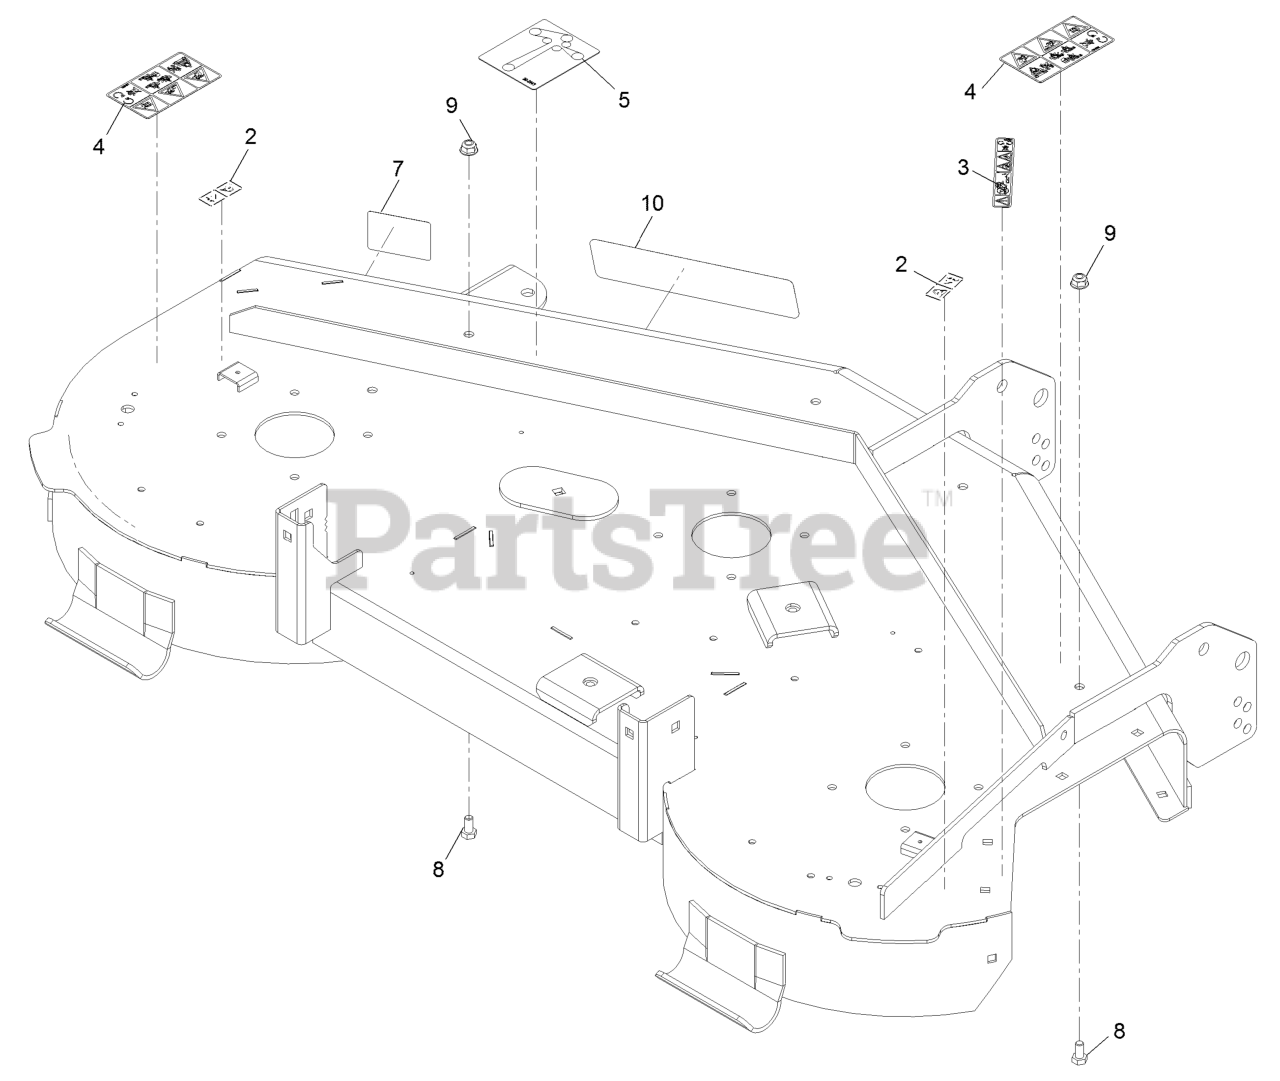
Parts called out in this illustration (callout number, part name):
2	DECAL-DANGER
3	DECAL-DANGER
4	DECAL-DANGER
5	DECAL-ROUTING, BELT
7	DECAL-SCALP, ANTI
8	SCREW-HH
9	NUT-HF, NI
10	DECAL-SERIES 2 - 50
